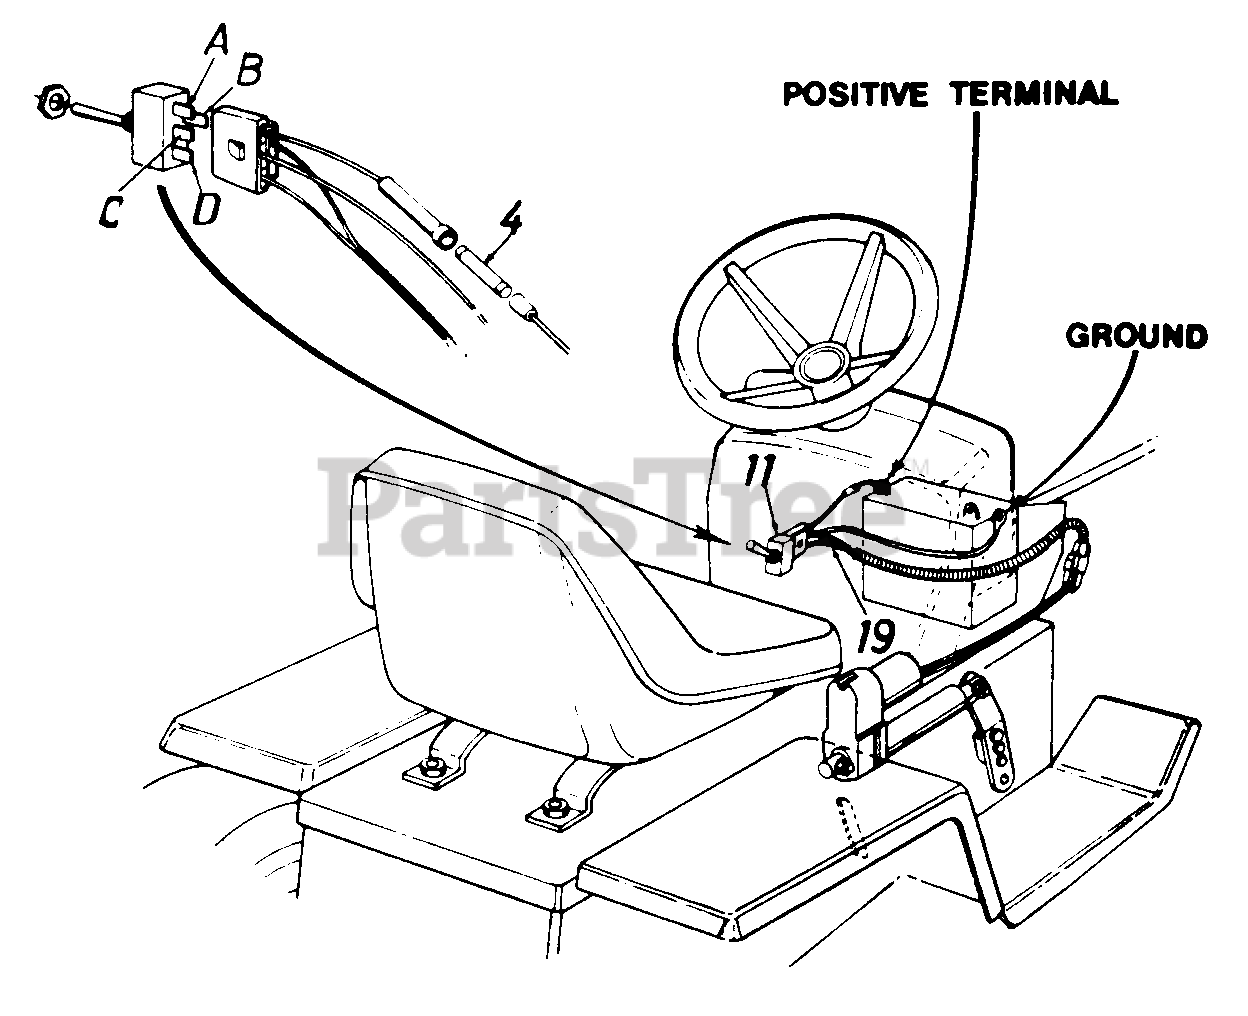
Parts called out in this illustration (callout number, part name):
4	Fuse 30 AMP
11	Toggle Switch
19	Wire Harness
A	Blue Wire-Connects to Positive Terminal on Battery
B	Yellow Wire-Connects to Actuator
C	Black Wire-Ground Wire -to Frame
D	Red Wire-Connects to Actuator
